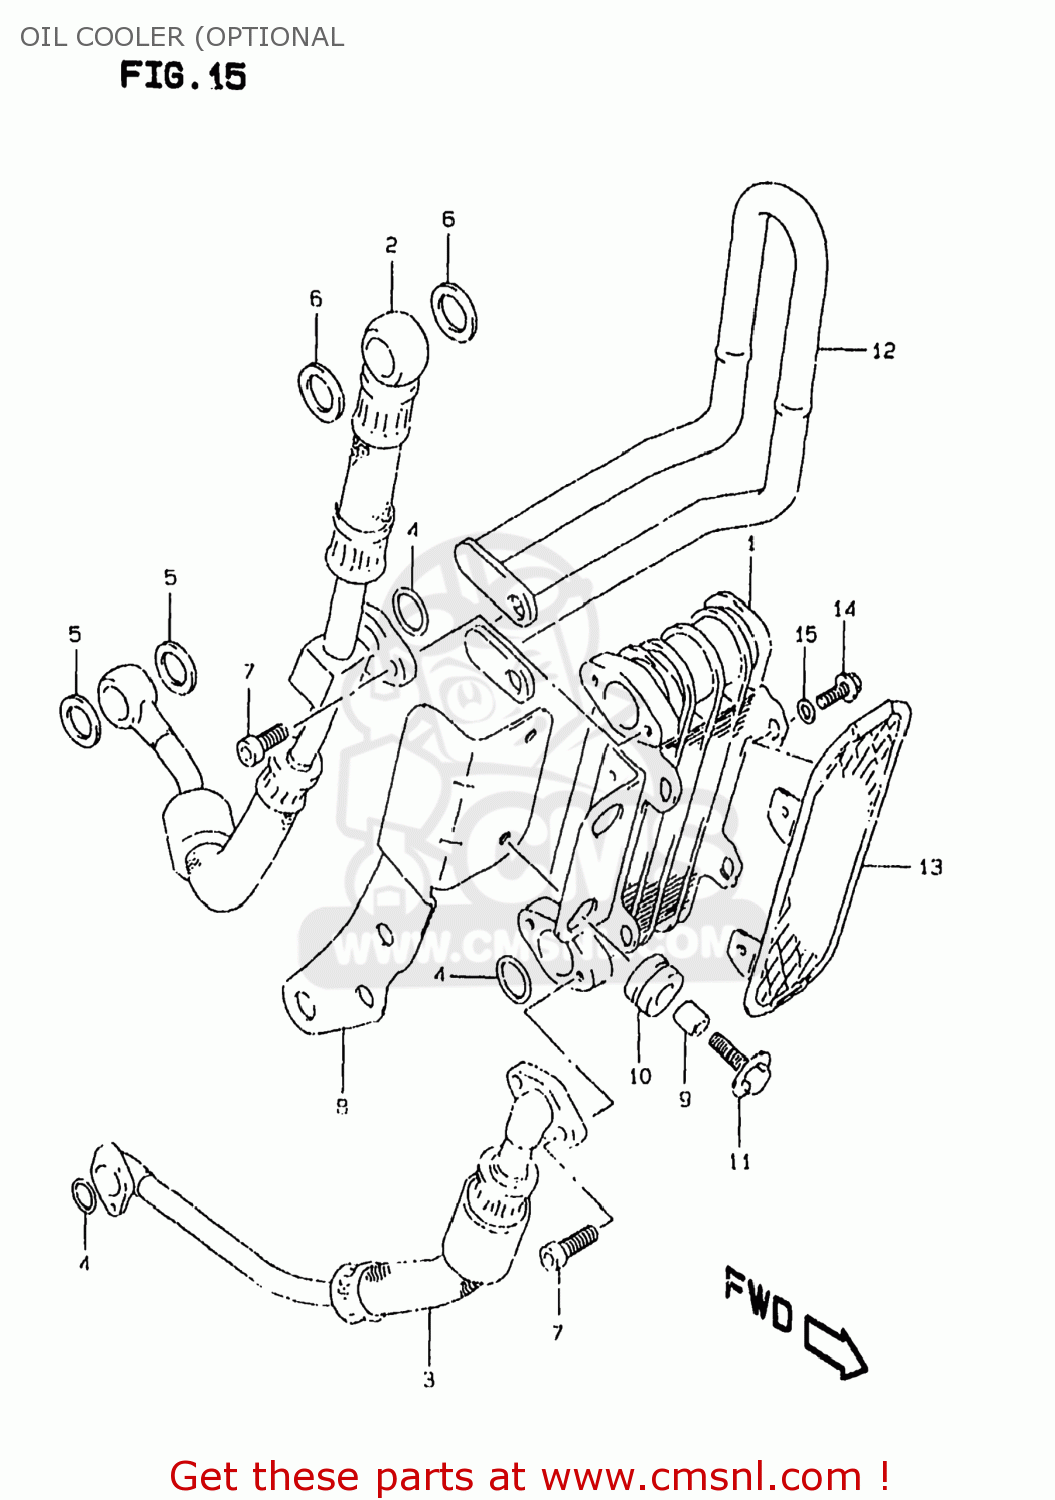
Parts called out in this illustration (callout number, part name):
1	COOLER ASSY,OIL
2	HOSE,OIL COOLER UPR
3	HOSE,OIL COOLER LWR
4	O RING(D:2.4,ID:12.3)
5	GASKET(12X17X1) (NAS)
6	GASKET(16X22X2) (NAS)
7	BOLT,OIL FILLE
8	BRACKET,OIL COOLER
9	SPACER(6.5X10X10)
10	CUSHION
11	BOLT 6X20
12	GUARD,OIL COOLER
13	BUMPER,OIL COOLER
14	BOLT
15	LOCK,WASHER
